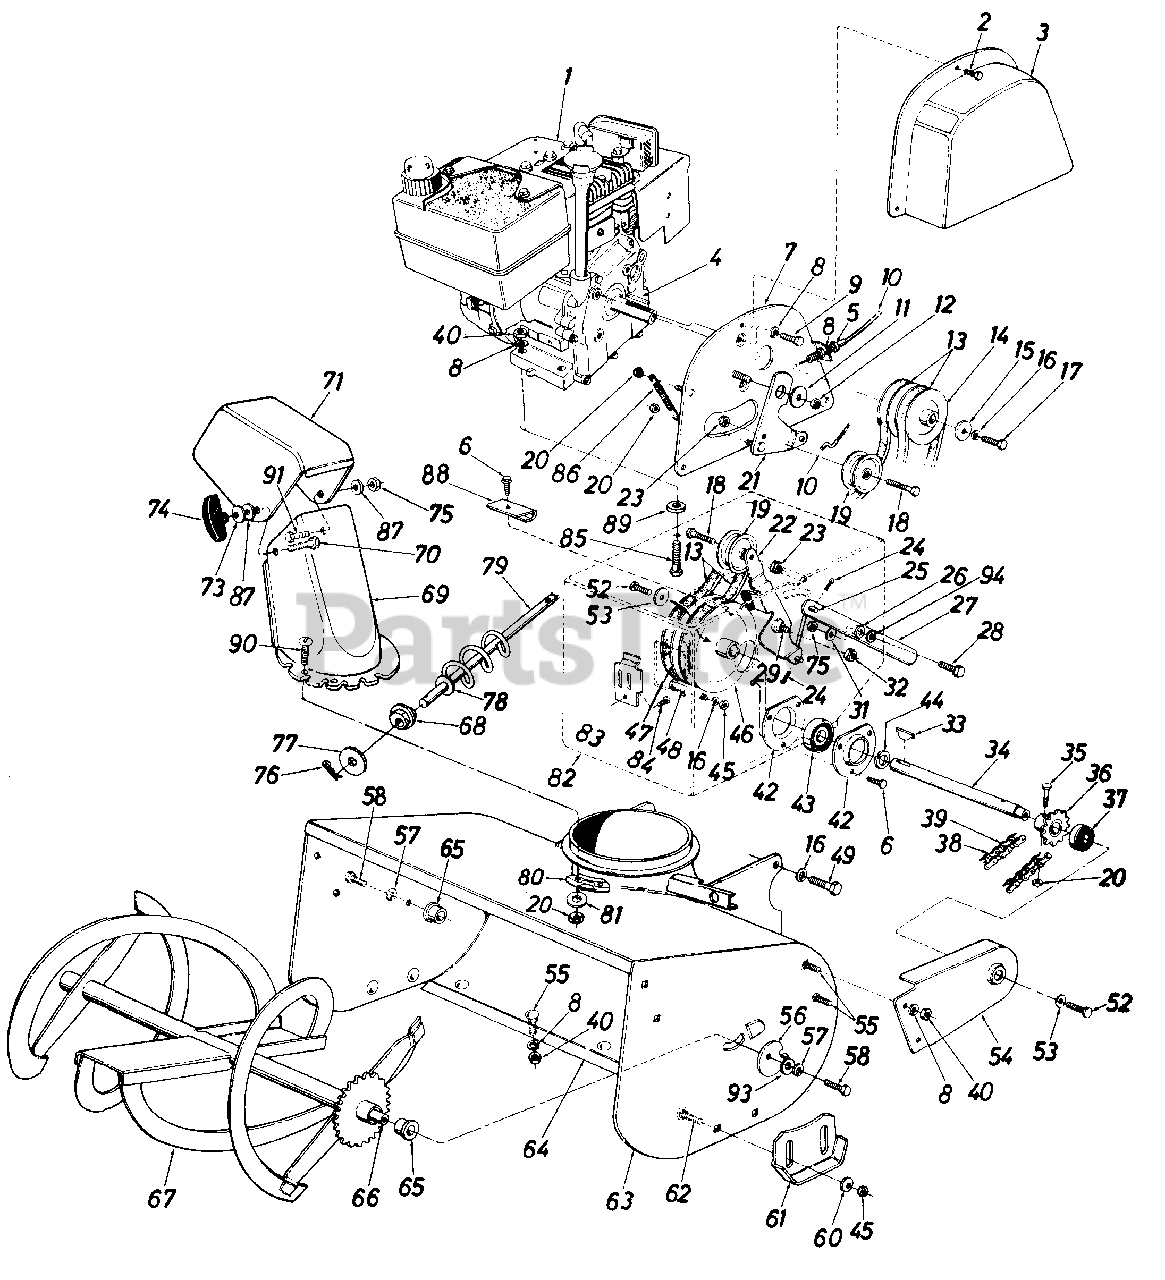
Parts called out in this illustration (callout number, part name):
1	Engine
2	Hex Bolt 1/4-20 x .50" Lg.*
3	Belt Cover
4	Sq. Key 3/16 x 1.00" Lg.
5	Hex Jam Nut 5/16-24 Thd.
6	Hex Wash. Hd. Self-Tap Scr. 5/16-24 x .50" Lg.
7	Engine Plate Ass'y.
8	L-Wash. 5/16" I.D.
9	Hex Bolt 5/16-24 x .62" Lg.
10	Drive Clutch Control Cable
11	Shld. Spacer
12	Hex Ins. Jam L-Nut 3/8-24 Thd.
13	V-Belt
14	Engine Pulley
15	Fl-Wash. .40 I.D. x 1.25 O.D. x .1 57
16	L-Wash. 3/8" I.D.
17	Hex Bolt 3/8-24 x 1.25" Lg.
18	Hex Bolt 3/8-16 x 1.25" Lg.*
19	Flat Idler 2.25 O.D.
20	Hex Cent. L-Nut 1/4-20 Thd.
21	Drive Idler Bracket Ass'y.
22	Thrower Idler Bracket Ass'y.
23	Hex Cent. Jam L-Nut 3/8-16 Thd.
24	Cotter Pin 3/32" Dia. x .75"
25	Clutch Rod 5/16" Dia. x 2.88 Lg.
26	Shoulder Spacer
27	Thrower Clutch Bracket
28	Hex Sems Scr. 5/16-18 x 1.00" Lg.
29	Shoulder Scr. .625" Dia. x .1 70"
31	Fl-Wash. .34 I.D. x 1.12 O.D. x .125
32	Hex Jam L-Nut 3/8-16 Thd.
33	Woodruff Key 5/32 x 5/8 Dia.
34	Thrower Shaft 20" and Snap Ring
35	Hex Bolt 1/4-20 x 1.5" Lg.
36	14 Teeth Sprocket Hub Ass'y.
37	Ball Bearing .625 I.D. x 1.38 O.D. x .438
38	#41 Chain-1/2" Pitch x 63 Links
39	#41 Master Link 1/2" Pitch
40	Hex Nut 5/16-18 Thd.
42	Bearing Housing
43	Self Align. Brg. .750 I.D.
45	Hex Jam Nut 3/8-16 Thd.
46	1/2" V-Pulley .753 I.D.
47	5.25" O.D. Pulley with 9 Teeth Sprocket
48	Shoulder Scr. .498" Dia. x 2.62" Lg.
49	Hex Self-Tap Scr. 3/8-16 x .75"
52	Hex L-Bolt 5/16-18 x .62" Lg.
53	Belleville Wash. .34 I.D. x .88 O.D. x .060
54	Chain Guard
55	Carriage Bolt 5/16-18 x .62" Lg.
56	Chain Adjuster
57	L-Wash. 3/8" I.D.
58	Hex Scr. 3/8-24 x 1.0" Lg.
60	Belleville Wash. .40 I.D. x .88 O.D.
63	Spiral Housing Ass'y. 20"
66	Spiral Shaft
67	Spiral Ass'y.-20"
68	Hex Bushing
69	Lower Chute
70	Carriage Bolt 5/16-18 x 1.0"
71	Upper Chute
73	Belleville Wash. .34 I.D. x .88
74	Handle Knob Ass'y.
75	Hex Cent. L-Nut 5/16-18 Thd.
76	Cotter Pin 3/32" Dia. x .75"
77	Fl-Wash. .406" I.D. x 1.25"
78	Fl-Wash. .385" I.D. x .62"
79	Chute Crank Ass'y. 10" Lg.
80	Chute Flange Keeper
81	Fl-Wash..281" I.D.
82	Frame Ass'y.
83	Belt Guard Plate
84	Hex Wash. Self-Tap Scr. 5/16-18 x .75" Lg.
85	Hex Scr. 5/16-18 x 1.50" Lg.
86	Ext. Spring .38 O.D. x 2.50"
87	Fl-Wash. .344 I.D.
88	Belt Guard
89	Fl-Wash. .34 I.D. x .62 O.D. x .060
90	Truss Mach. Scr. 1/4-20 x .75"
91	Truss Mach. Scr. 5/16-18 x .75"
93	Fl-Wash. .385" I.D. x 1.0" O.D.
94	Fl-Wash. .33" I.D. x 1.25" O.D.
